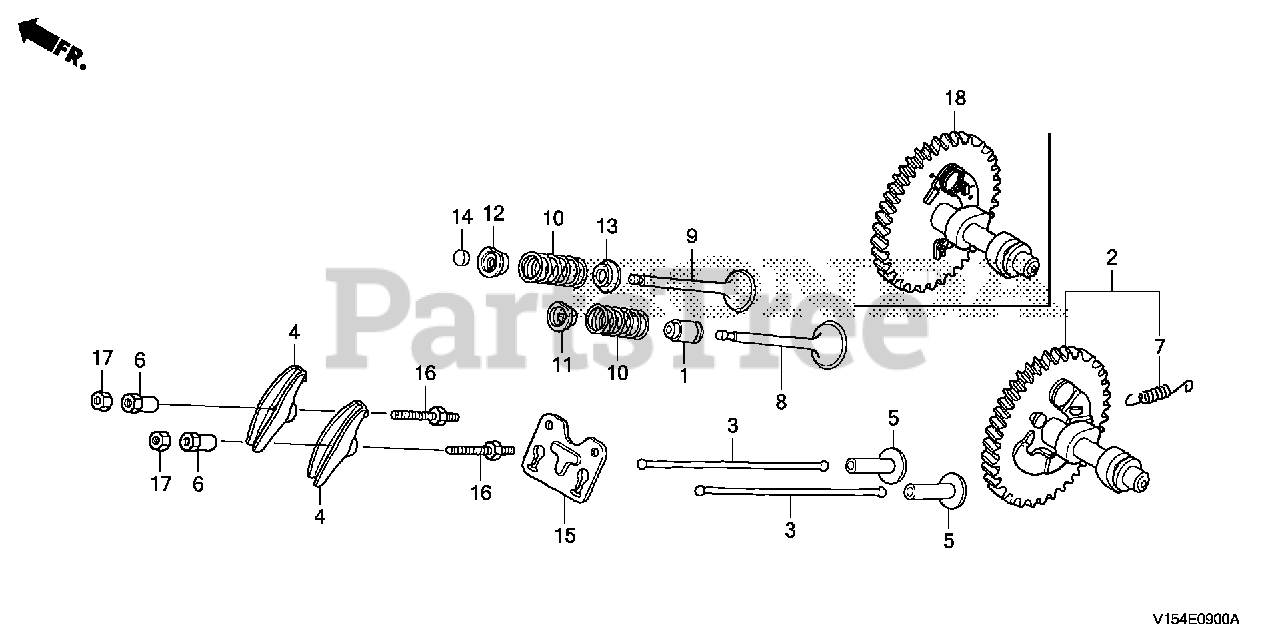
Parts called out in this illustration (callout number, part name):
1	SEAL, VALVE STEM
4	ARM, VALVE ROCKER
5	LIFTER, VALVE
6	PIVOT, ROCKER ARM
8	VALVE, IN.
9	VALVE, EX.
10	SPRING, VALVE
11	RETAINER, IN. VALVE SPRING
12	RETAINER, IN. VALVE SPRING (EXHAUST SIDE)
13	SEAT, VALVE SPRING
15	GUIDE, PUSH ROD
16	BOLT, PIVOT (8MM)
17	NUT, PIVOT ADJUSTING
18	CAMSHAFT (STD)
